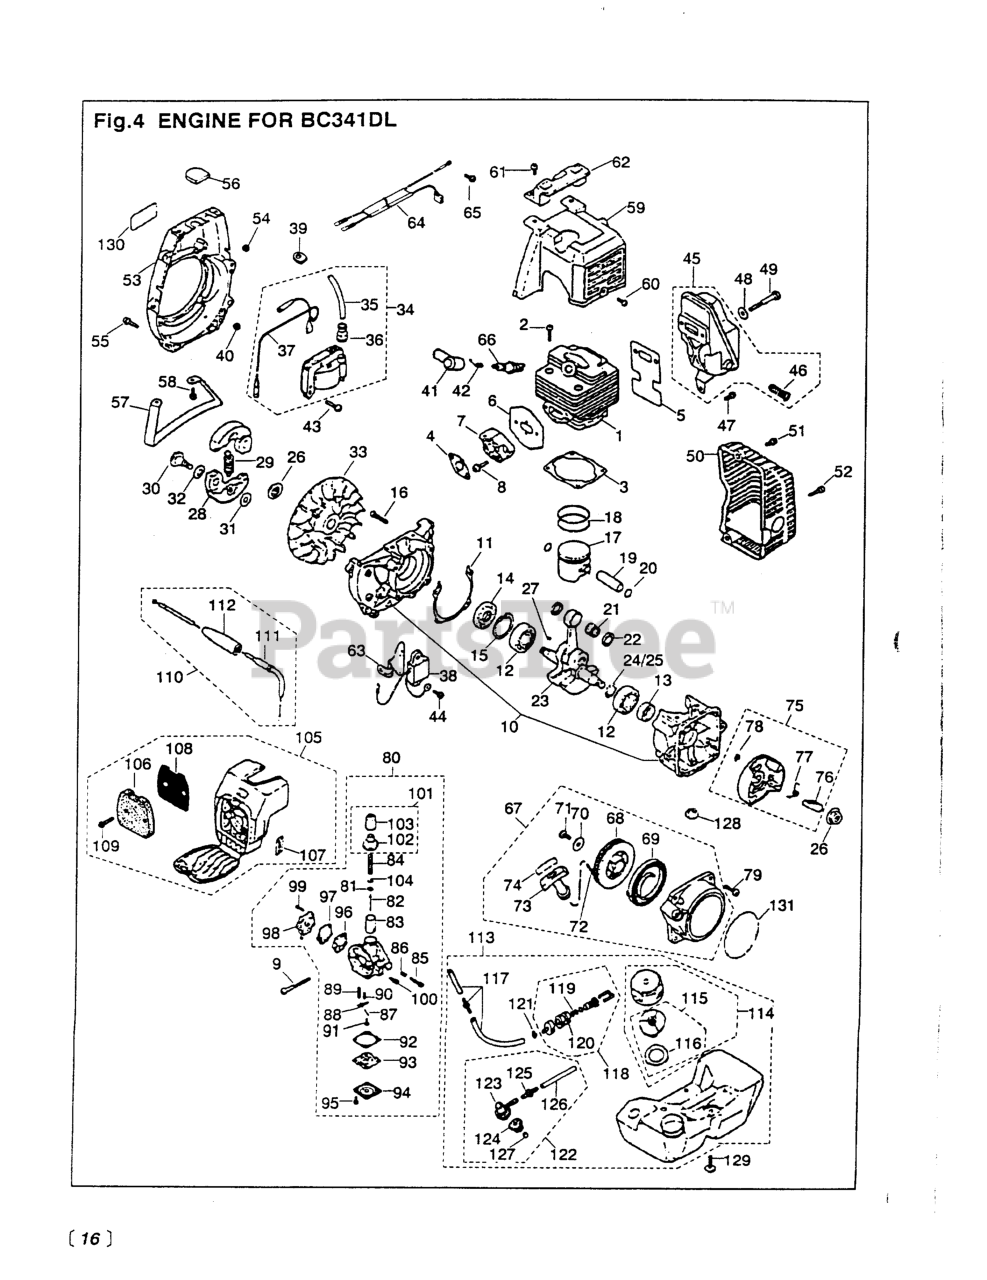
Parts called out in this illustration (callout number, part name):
3	GASKET
7	INSULATOR
8	SCREW (USE 0263-90520 )
9	SCREW, M5 x 45
10	CRANKCASE (RPLS -21101)
14	SEAL, OIL (RPLS 1200-21220)
15	RING, SNAP, M32 x 1.2
16	SCREW, M5 x 30(RPLS 0263-00530
18	RING, PISTON
19	PIN
20	RING, SNAP
21	BEARING
22	WASHER (RPLS 3310-41341)
23	CRANKSHAFT CO
24	SHIM (NO LONGER AVAILABLE)
27	KEY
29	SPRING, CLUTCH
30	SCREW
31	WASHER
34	COIL ASSEMBLY
35	CORD
36	CAP
38	UNIT (RPLS -71310)
41	CAP, PLUG
42	SPRING PLUG (RPLS 3310-71320)
43	SCREW (USE 0263-90520 )
44	SCREW, M5 X 14
45	MUFFLER ASSEMBLY
46	ARRESTER
48	WASHER, FLAT (USE 182303)
49	BOLT, M6 X 55
50	COVER, MUFFLER
51	SCREW (USE 0263-90520 )
52	SCREW, M5 X 30
55	SCREW, M5 X 20
61	SCREW (USE 0263-90520 )
62	HEAD GUARD
67	RECOIL ASSEMBLY
68	REEL
69	SPRING, SPIRAL
73	KNOB
75	PULLEY ASSEMBLY
76	RATCHET
77	SPRING, RETURN
78	E-RING
79	SCREW (USE 0263-90520 )
81	RETAINER SPRING
85	SCREW (RPLS -81161)
88	ARM, FLOAT
89	VALVE (USE -81211)
90	SPRING, INLET
91	SCREW, FLOAT
92	GASKET (NLA)
93	DIAPHRAGM
95	SCREW, M3 X 8
96	GASKET, PUMP
97	DIAPHRAGM
98	COVER ASSY PU
99	SCREW, M3 x 12
100	NEEDLE (NLA)
102	CAP, MIXING
103	SEAL, AIR
105	CLEANER ASSY (USE -82002)
106	ELEMENT
107	LABEL
109	SCREW, M4 X 22
112	PROTECTOR
113	TANK ASSEMBLY (USE -85003)
115	VALVE COMPLETE
116	PACKING (RPLS -85321)
117	PIPE ASSEMBLY
118	FILTER ASSY
121	CLIP (REPLACES 2841-31280)
128	WASHER
129	SCREW, M5 X 22
131	LABEL (USE -75412)
